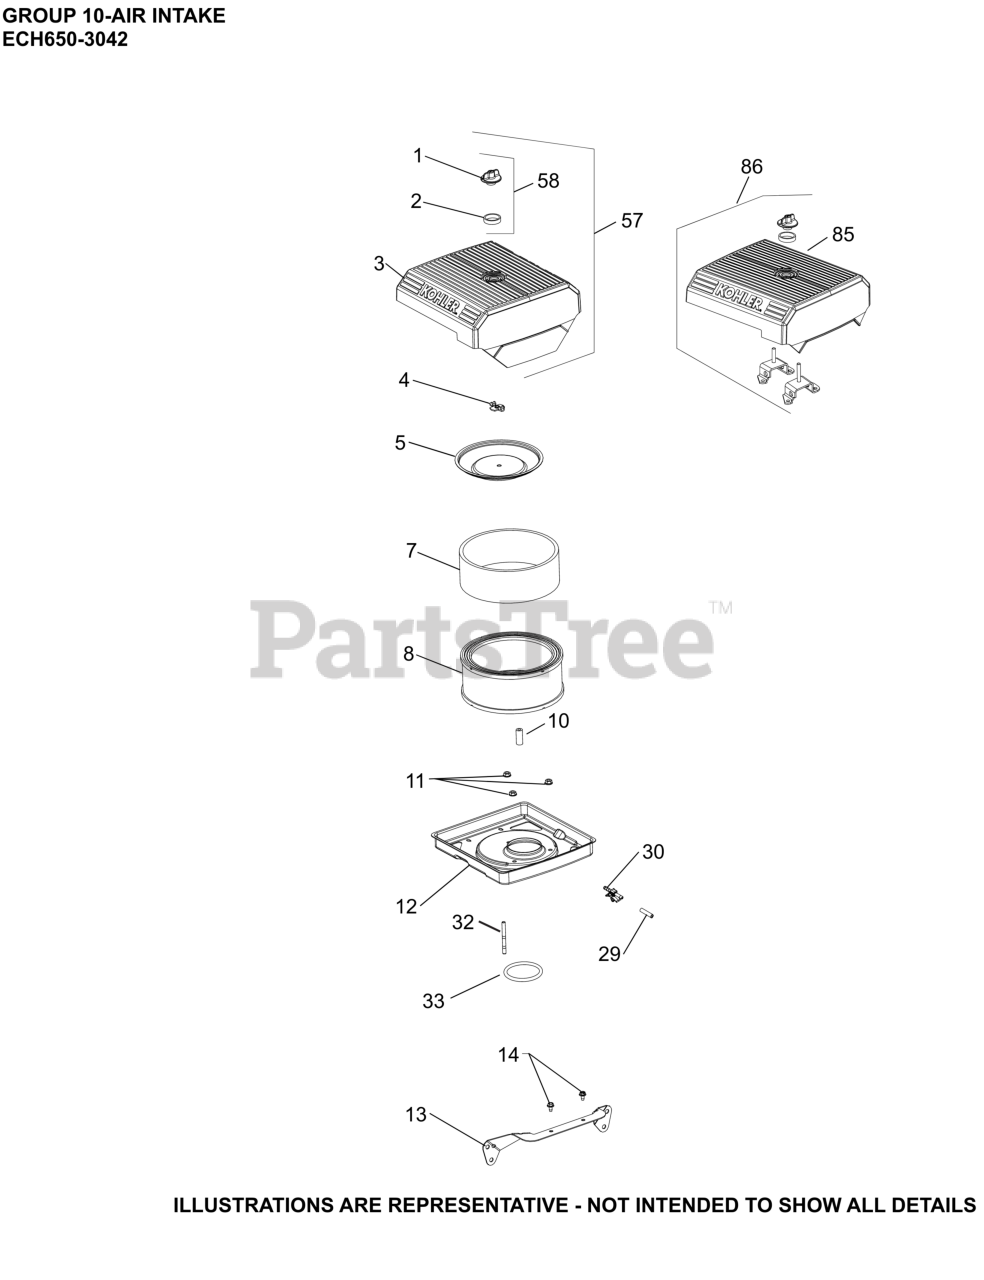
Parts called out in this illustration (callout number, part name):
1	KNOB, COVER
3	COVER, AIR CLEANER
4	NUT, WING
5	COVER, INNER AIR CLEANER
7	PRE CLEANER LOW ELEMENT
8	ELEMENT, AIR CLEANER
11	NUT, FLG M6X1.0
12	BASE, AIR CLEANER
13	AIR CLEANER BRACKET
14	SCREW, THREAD FORMING
29	CAP, MASKING
30	CONNECTOR, EVAPORATIVE
32	STUD, LOW PROFILE A/C
33	O-RING, AIR CLEANER BASE
57	KIT, AIR CLEANER COVER
58	KIT, KNOB W/SEAL
NI	COVER, AIR CLEANER
NI	KIT, AIR CLEANER COVER
